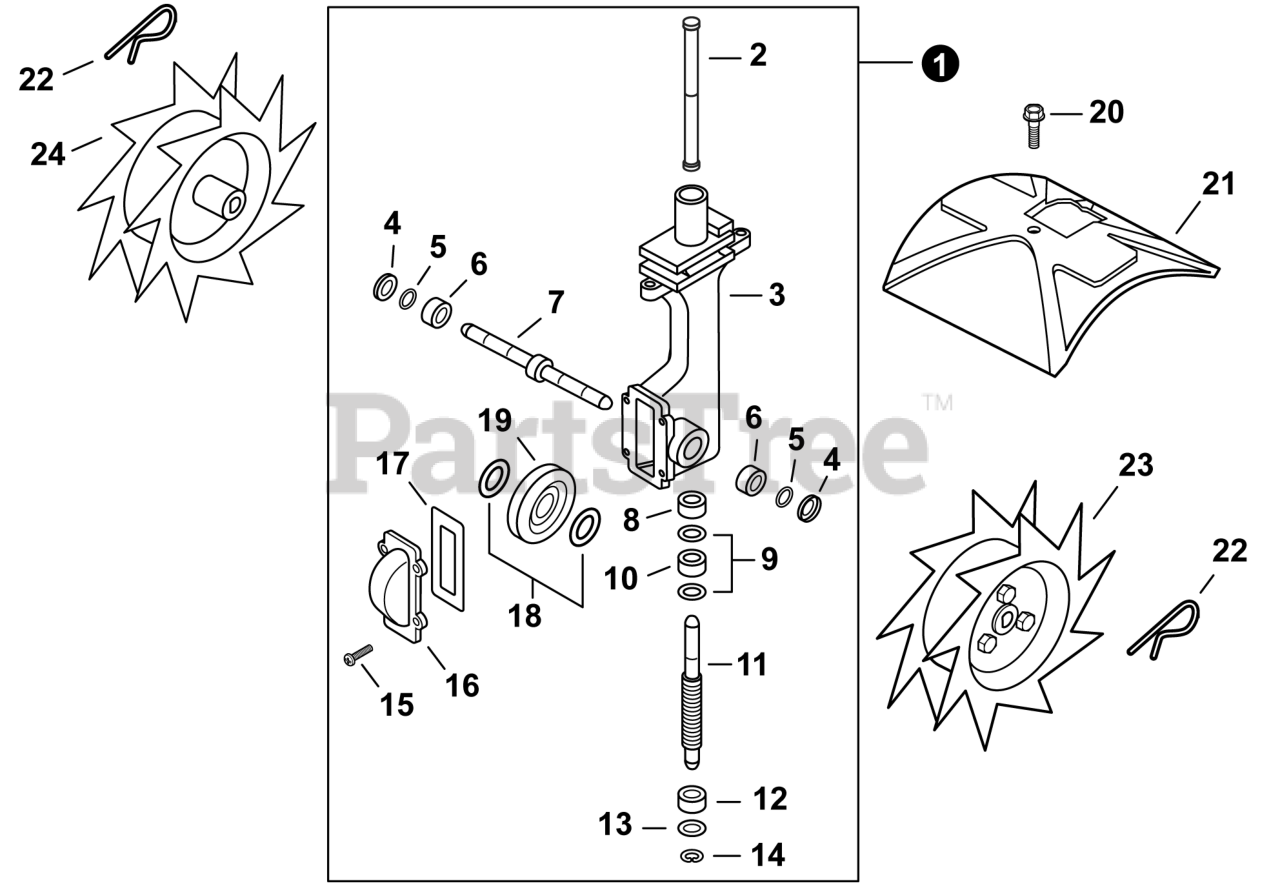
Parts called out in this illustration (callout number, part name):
1	GEAR CASE ASSY
2	DRIVESHAFT
3	CASE, GEAR
5	RETAINER
6	BEARING, NEEDLE
8	BEARING, NEEDLE
10	BEARING, THRUST
11	GEAR, WORM
12	BEARING, ROLLER
14	RING, RETAINING
15	SCREW, TAPPING
16	COVER, GEAR CASE
17	GASKET, GEAR CASE
18	WASHER, THRUST 8
19	GEAR, WORM
20	BOLT 1/4"x1/2"
21	SHIELD, DEBRIS
22	PIN, SNAP
23	TINE, RIGHT
24	TINE, LEFT
